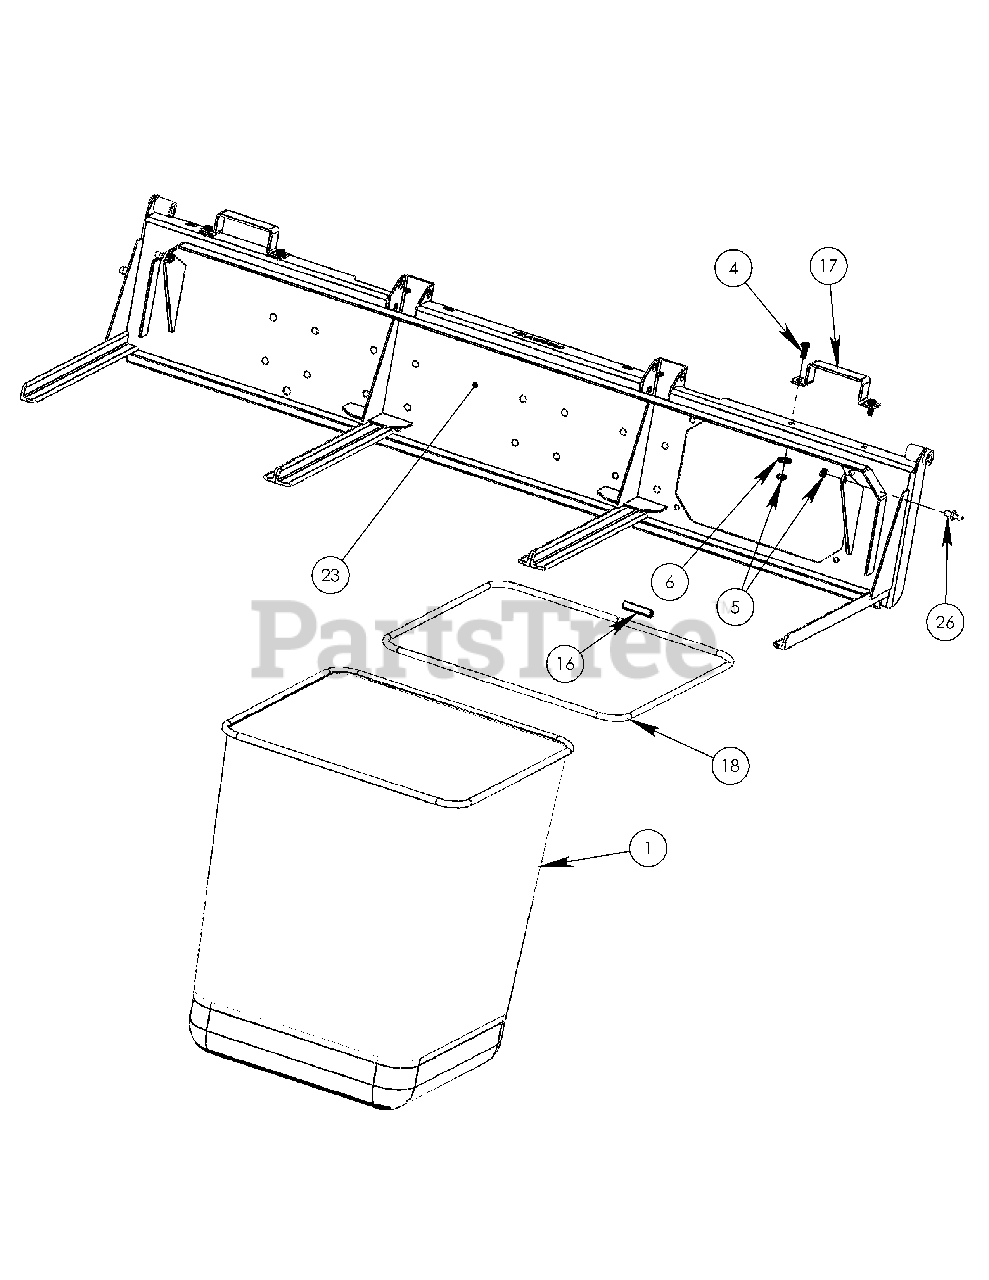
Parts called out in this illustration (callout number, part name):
1	Catcher Bag, Commerical
2	Air Dome (3-Bag) Extened
3	1.5" Hole Plug, Plastic
4	Cap Screw 5/16-18 X .75
5	5/16-18 Nylon Insert Nut
6	5/16" Flat Washer
7	1/2 Detent Pin 2.5" Long
8	Cap Screw 1/4-20 X .75
9	1/2-13 Nylon Insert Nut
10	1/2" Flat Washer
11	1/4" Uss Washer
12	1/4" Lockwasher
13	Pan Head Cap Screw 5/16-18 X3/4 Lg
14	CS 1/2-13 X 2.5 G5
15	CS 1/2-13 X 3 G5
16	Tube, Plastic 1/2" OD X 3/8 ID
17	Handle, Bag
19	Gas Cylinder Mount
20	Bracket Mount
21	Air Dome Frame (3-Bag)
22	3 -Bag Deflector
23	3-Bag Support Mount
24	3 Bag Raised Cap Support
25	Gas Cylinder, 6X15 Lom 375 Ext
26	Ball Joint
